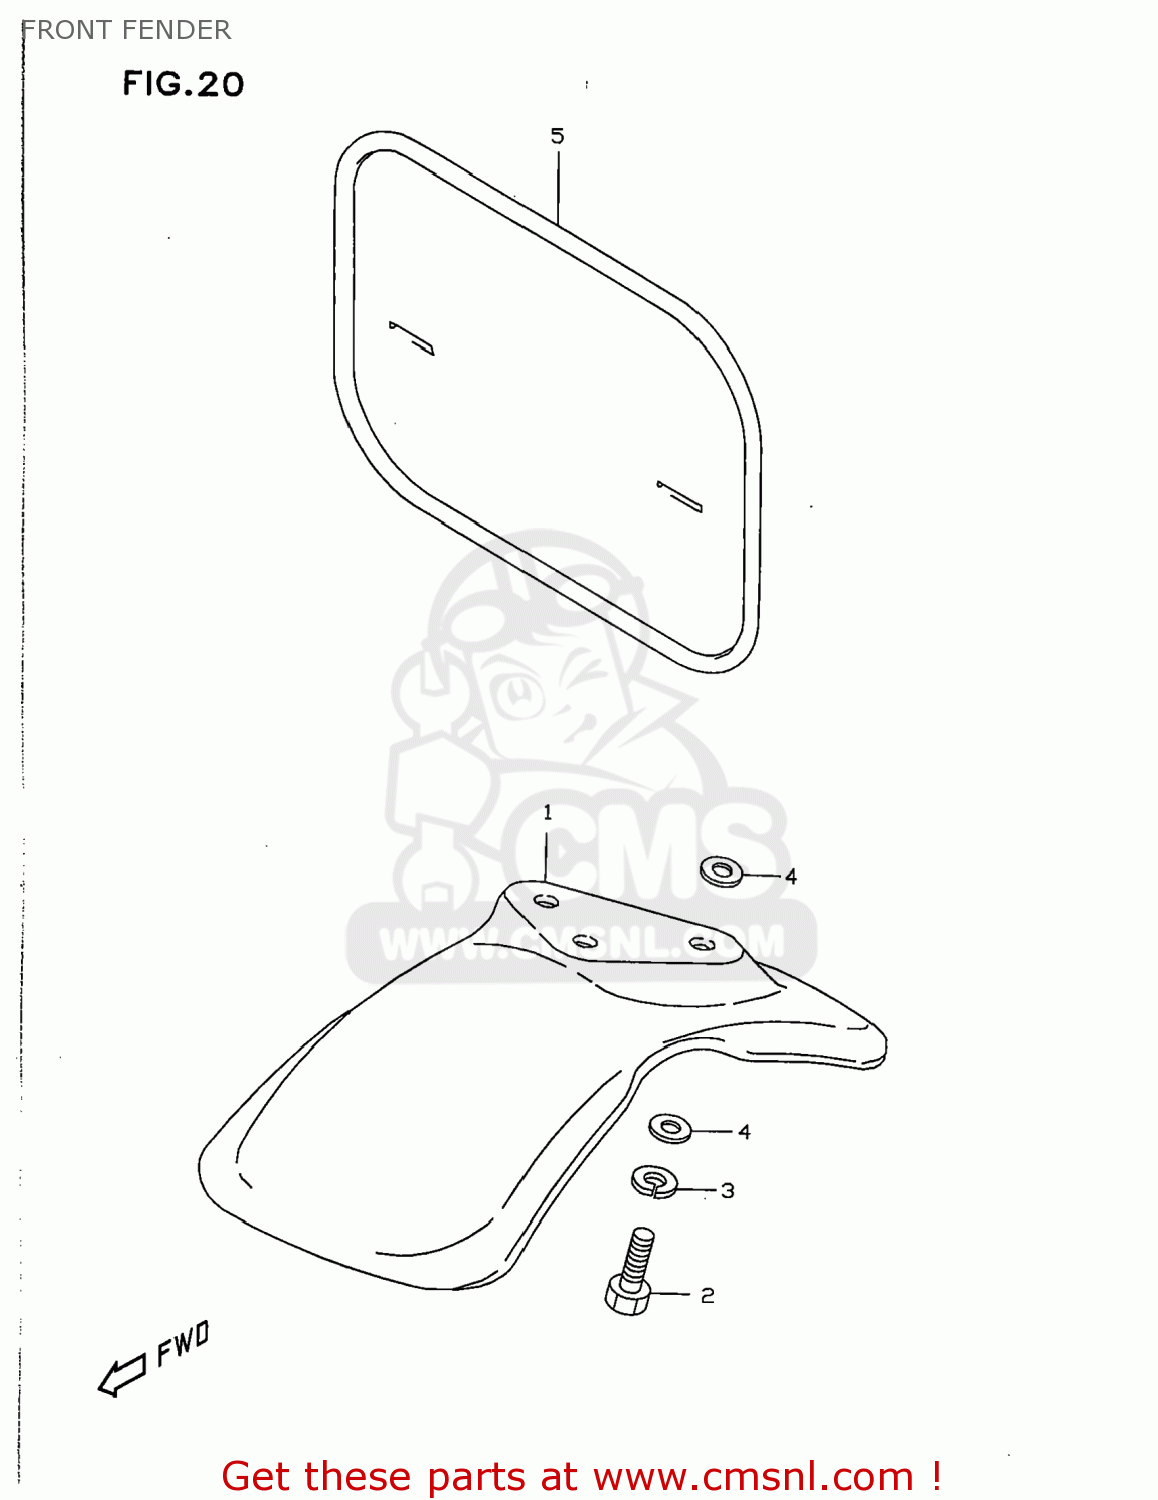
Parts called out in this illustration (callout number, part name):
1	FENDER,FR
2	BOLT
3	LOCK WASHER
4	WASHER(6.5X18X1)
5	PLATE,NUMBER FR
